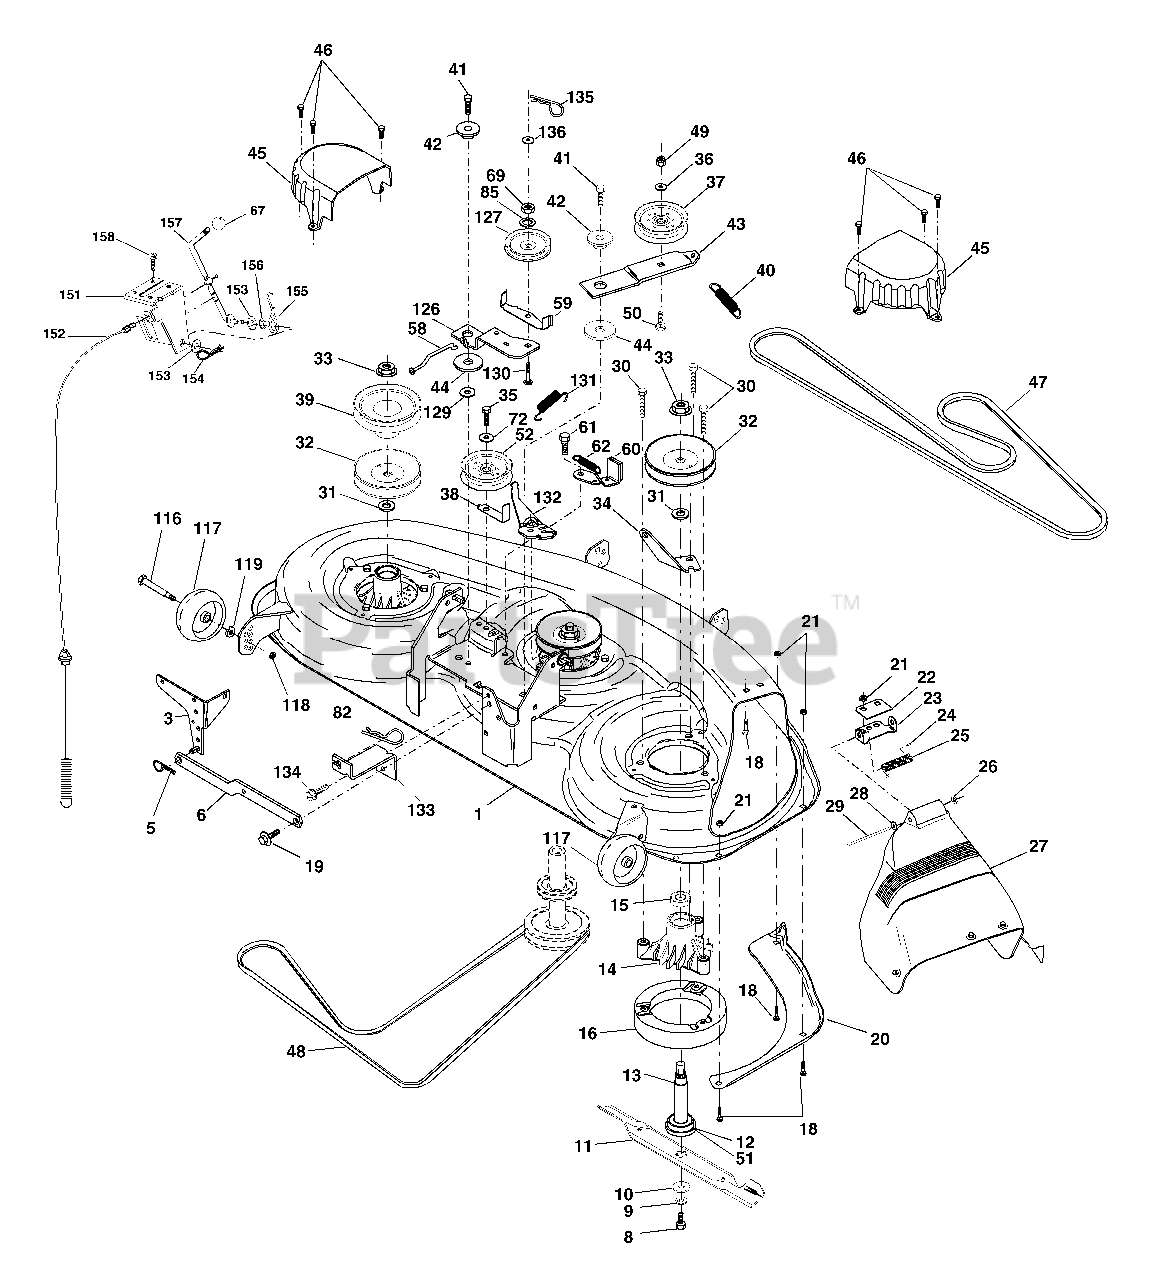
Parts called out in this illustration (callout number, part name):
1	Deck Asm., Mower 46"
3	Bracket Asm., Sway Bar
5	Retainer Spring
6	Arm, Suspension, Rear (Sway Bar)
8	Bolt, Patched 3/8-24 x 1-1/4 Gr. 8
9	Washer, Lock Hvy., Unplated 3/8
10	Washer, Hard Blade, Mower Vented
11	Blade, 46" Mower Deck
12	Bearing, Ball, Mandrel #6204
13	Shaft Asm. w/Lower Bearing
14	Housing, Mandrel
15	Bearing, Ball, Mandrel
16	Stripper, Mower Round
18	Bolt, Carriage 5/16-18 x 5/8
19	Bolt, Hex Head, Shoulder 5/16-18
20	Baffle, Vortex Mower 46"
21	Nut, Crownlock 5/16-18 UNC
22	Stiffiner, Bracket
23	Bracket, Deflector
24	Cap, Sleeve
25	Spring, Torsion, Deflector
26	Nut, Push
27	Shield, Deflector Mower
28	Washer 11/32 x 5/8 x 16 Ga.
29	Rod, Hinge
30	Screw Thd Rolling Washer Head
31	Washer, Spacer Mower Vented
32	Pulley, Mandrel
33	Nut, Flg. Top Lock Cntr. 9/16
34	Anchor, Spring Deck 46"
35	Screw, Thdroll 3/8-16 x 1-3/4 Tytt
36	Washer 13/32 x 13/16 x 16 Ga.
37	Pulley, Idler, Flat
38	Keeper, Belt, Idler
39	Pulley, Idler, Driven
40	Spring, Secondary 44/46/50 Vent
41	Screw, Thdroll 3/8-16 x 1-1/4
42	Spacer, Retainer
43	Arm, Idler Secondary
44	Washer, Hardened
45	Cover, Mandrel Deck
46	Screw, Thdroll. 1/4-20 x 5/8
47	V-Belt, Mower, Secondary
48	V-Belt, Mower, Primary
49	Nut, Crownlock 3/8-16 UNC
50	Bolt, Carriage 3/8-16 x 1-1/2 Gr. 5
51	Washer, Felt
52	Pulley, Idler, Flat
58	Rod Brake 46"
59	Guide, Belt 46" Mower
60	Arm Asm. Brake 46"
61	Bolt, Shoulder 5/16-18 Type TT
62	Spring Return
67	Knob Rd 3/8-16 Plstc Thds Blk
69	Nut, Hex Jam 3/8-16 Unc
72	Washer 13/32 x 13/16 x 16 Ga.
82	Retainer Spring 1"
85	Washer, Lock Hvy Hlcl Spr 3/8
116	Bolt, Shoulder
117	Gauge Wheel
118	Nut, Centerlock 3/8-16 UNC
119	Washer 3/8 x 7/8 x 14 Ga.
126	Arm, Idler, Deck 46" Mech.
127	Pulley, Idler, V-Groove Dim. 4.25
129	Washer 13/32 x 2-3/8 x 8 Ga.
130	Bolt Carriage Idler
131	Spring Return Idler
132	Arm Spring Brake Mower
133	Bracket Anchor Cable 46"
134	Screw Thdrol 5/16-18 x 3/4
135	Retainer Spring Yellow
136	Washer 9/32 x 3/4 x 16 Ga
151	Bracket Clutch Cable
152	Clutch Cable 38"/46"
153	Washer Flat 3/8" Type B
154	Spring Retainer
155	Spring Retention Q
156	Spacer Clutch Cable
157	Rod Clutch Cable 38"
158	Screw Hex Thd Cut 1/4-20 x 5/8
